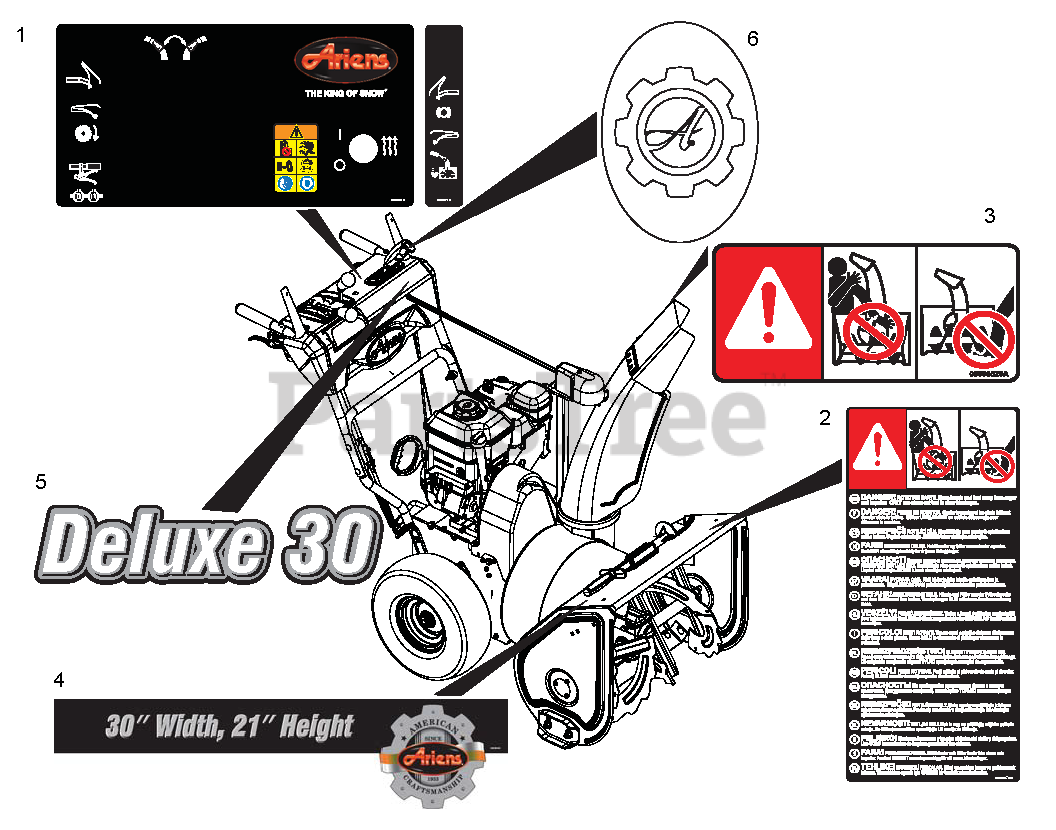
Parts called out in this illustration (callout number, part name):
1	DECAL, CONTROL - DLX PIN-LOCK
2	DECAL, DANGER - ROTATING PARTS
3	DECAL, DANGER
5	DECAL, DELUXE 30
6	DECAL, ARIENS GEAR - RAISED
